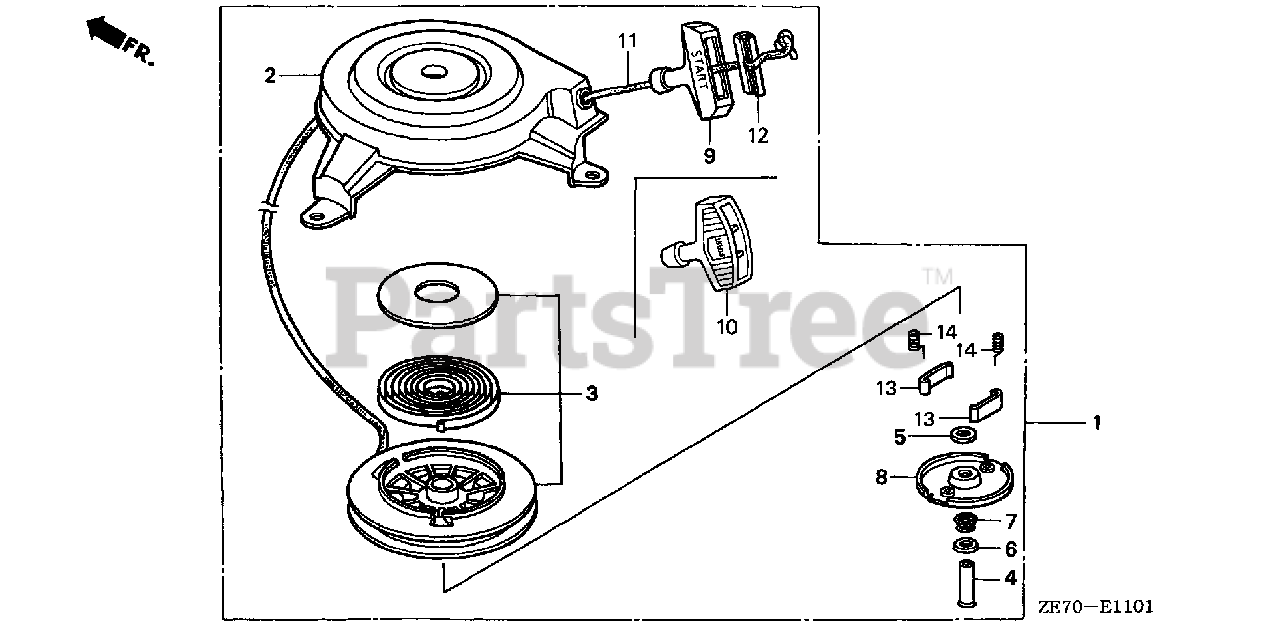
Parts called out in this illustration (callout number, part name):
1	STARTER ASSY., RECOIL
2	HOUSING ASSY.
3	PULLEY & SPRING ASSY.
4	PIN, CENTER
5	PLATE A, FRICTION
6	PLATE B, FRICTION
7	SPRING, FRICTION
8	RETAINER
9	HANDLE
11	ROPE, RECOIL STARTER (#4X85")
12	HANDLE, REINFORCEMENT
13	RATCHET, STARTER
14	SPRING, DOG
